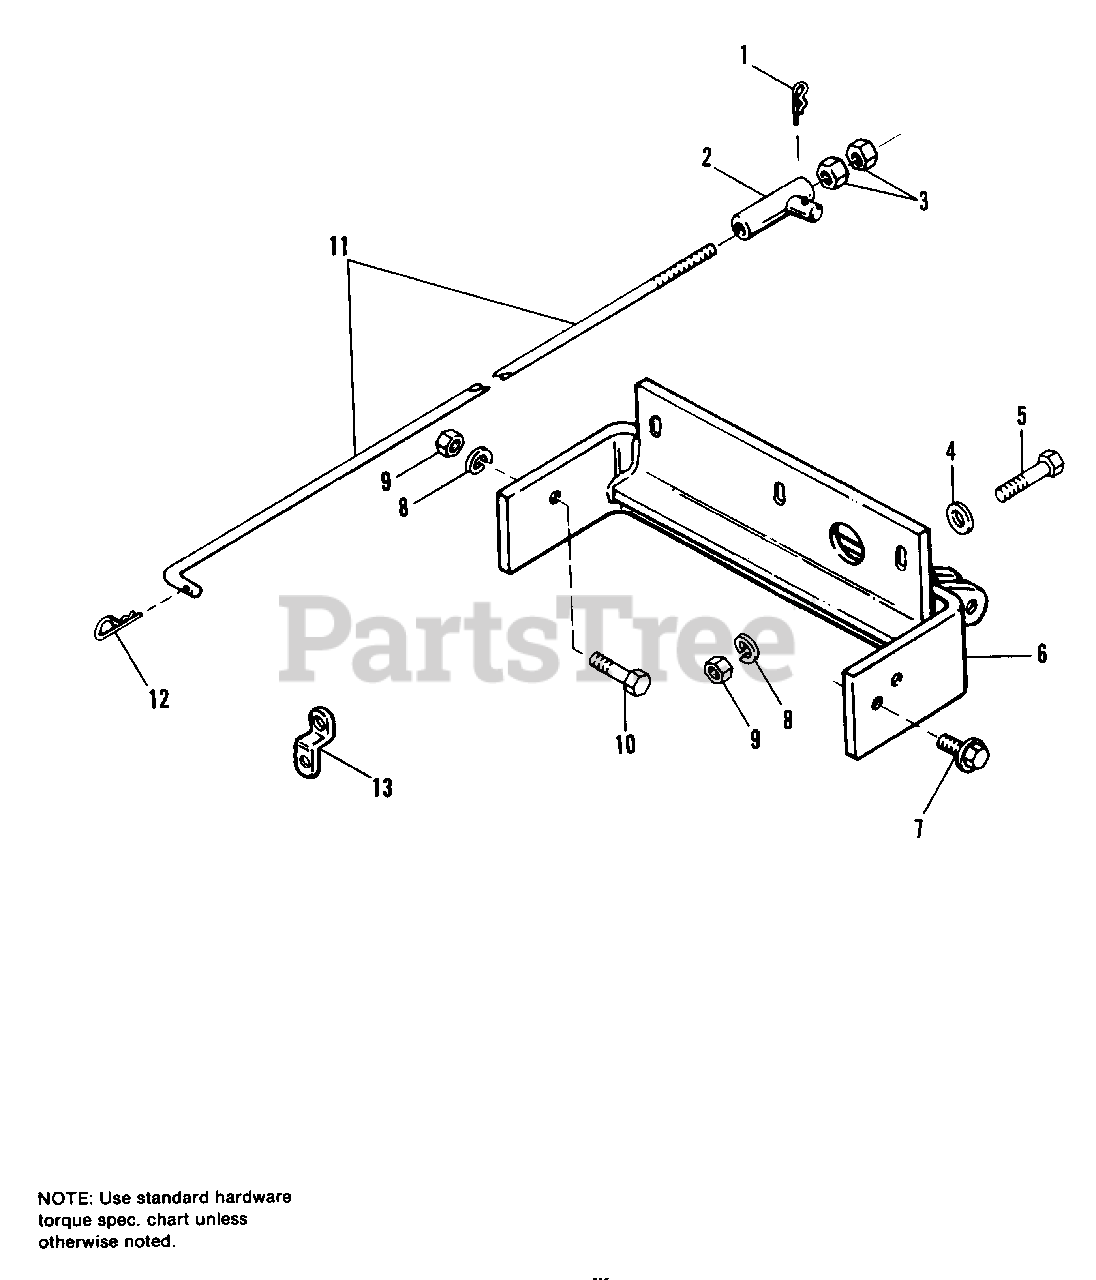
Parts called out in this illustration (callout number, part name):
1	PIN, Quick
2	TUBE ASSY., Guide
3	NUT, Jam, 1/2-20
4	WASHER, 3/8
5	CAPSCREW, 3/8-16 x 1
7	CAPSCREW, Whizlock, 3/8-16 x 1-1/4
8	LOCKWASHER, 3/8
9	NUT, Hex, 3/8-16
10	CAPSCREW, Hex, 3/8-16 x 7/8
11	ROD, Lift
12	CLIP, Hairpin
13	CLIP, Spring
